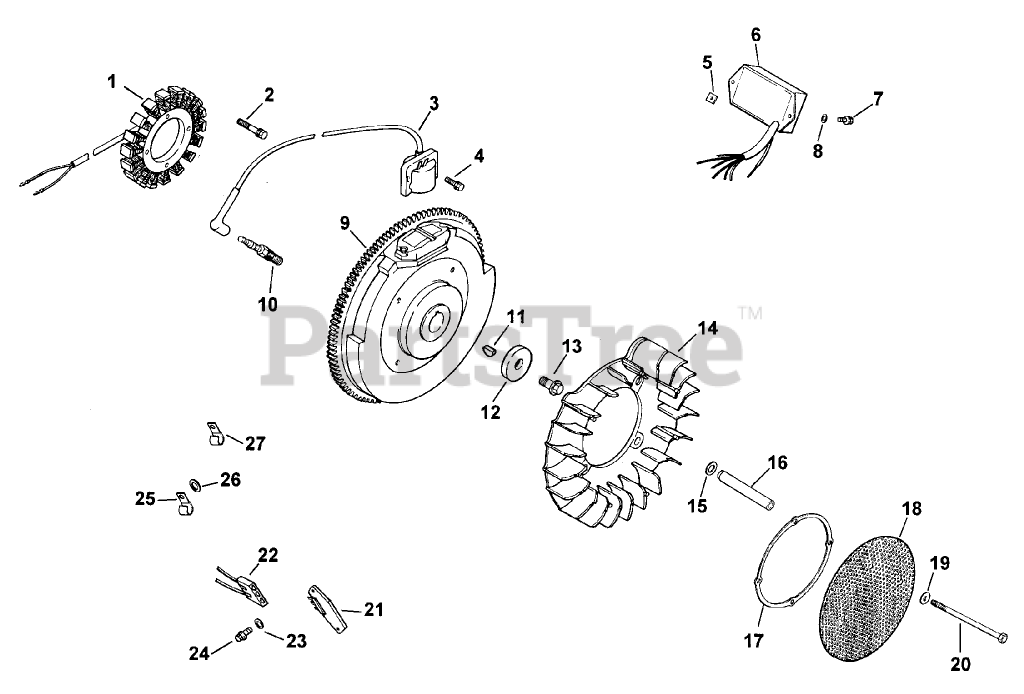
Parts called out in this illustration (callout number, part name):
1	Stator-15 amp
2	Screw
3	Module-Ignition
4	Screw-HSH
5	Nut-Plastic
6	Module, speed adv.
7	Screw, pan head M4.2x13 (2)
8	Washer
9	Flywheel
10	Plug-Spark
11	Key
12	Washer
13	Screw
14	Fan
15	Washer, sping
16	Spacer
17	Ring-Support
18	Screen-Grass
19	Washer
20	Screw-Hex
21	Rectifier-Regulator
22	Connector
23	Washer
24	Screw
25	Clamp
26	Washer
27	Clip
